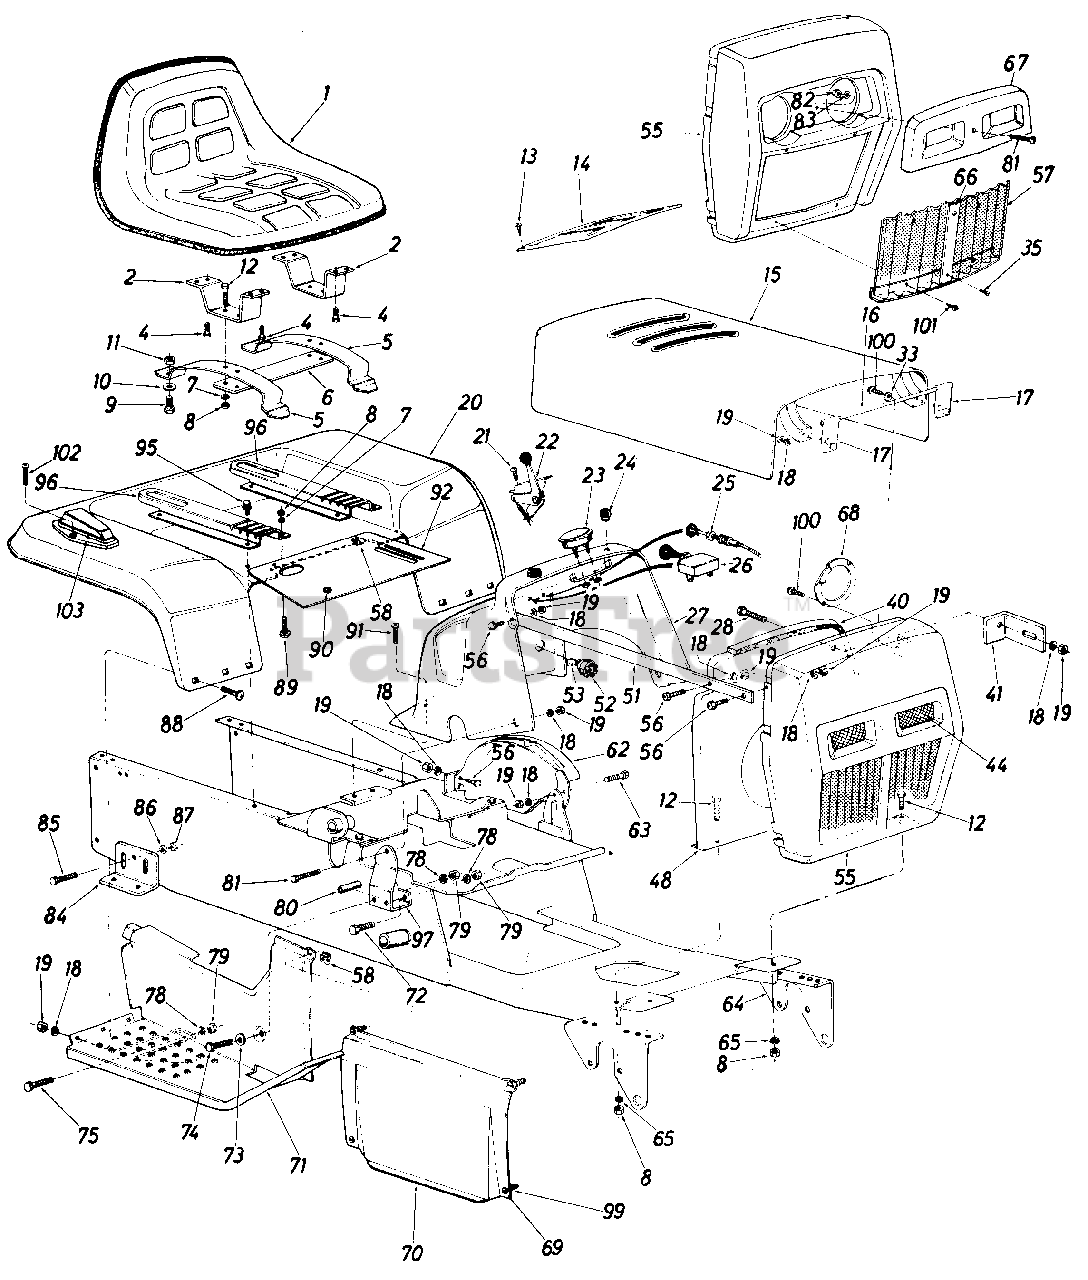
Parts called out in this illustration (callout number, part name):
1	Seat Ass'y. Comp.
2	Seat Support Brkt.
4	Hex Wash. Hd. Self-Tap Scr. 3/8-16 x .75" Lg.
7	L-Wash. 5/16" I.D.
8	Hex Nut 5/16-18 Thd.
9	Nylon Scr. 1/2-13 x .75" Lg.
10	Fl-Wash. .531 I.D. x .930 O.D.
11	Hex Cent. L-Nut '/2-13 Thd.
12	Hex Scr 5/16-18 x .75" Lg.
13	Self-Tap Oval Hd. Scr. 1/2" Lg.
14	Dash Panel Cover
15	Hood Ass'y.
16	Hinge Rod
17	Hood Hinge Ass'y.
18	L-Wash. 1/4" Scr.
19	Hex Nut 1/4-20 Thd.
20	Rear Fender
21	Fl-Hd. Truss Scr. #10 x .62" Lg.
22	Throttle Control
23	Ammeter
24	Rubber Bumper
25	Choke Control
26	Light Switch
27	Dash Panel
28	Hex Scr. 1/4-20 x .62" Lg.
33	Fl-Wash. .250 I.D. x 1.25 O.D.
40	Foam Strip
41	Heat Shield Brkt.
44	Head Lamp
48	Heat Shield
51	Grille Strap
52	Ignition Switch
53	Ignition Key
55	Grille
56	Hex Scr. 1/4-20 x .75" Lg.
57	Grille Screen
58	Clip-On Receptacle
62	Speed Control Guide
63	Truss Mach. Scr. 1/4-20 x .75" Lg.
64	Frame Ass'y.
65	Bell-Wash. 5/16" Scr.
66	Moulding
67	Headlight Bezel
68	Headlight Retainer
69	1/4-Turn Stud
70	Hood Lower Side Panel
71	Foot Step Panel Ass'y.-R.H.
72	Hex Scr. 3/8-16 x 1.00" Lg. Grade 5
73	Fl-Wash. .385 I.D. x,.62 O.D.
74	Hex Bolt 3/8-16 x 3.00" Lg.
75	Hex Bolt 3/8-16 x 1.00" Lg. Grade 5
78	L-Wash. 3/8" I.D.
79	Hex Nut 3/8-16 Thd.
80	Spacer .375 I.D. x .62 O.D. x 2.00" Lg.
81	Truss Mach. Scr. #10-24 x 1.0" Lg.
82	Sq. Nut #10-24 Thd.
83	Ext. L-Wash. #10 I.D.
84	Transaxle Support Brkt.
85	Rd. Hd. Rib Neck Scr. 3/8-24
86	L-Wash. 3/8" Scr.
87	Hex Nut 3/8-24 Thd.
88	Carr. Bolt 1/4-20 x .50" Lg.
89	Carr. Bolt 5/16-18 x .62" Lg.
90	Snap Bushing
91	Fl-Hd. Self-Tap Scr. 1/4-20 x .62" Lg.
96	Seat Adjustment Brkt.
100	Thread Rolling Scr. 1/4"
101	Drive Scr. #7
102	Fl. C-Sunk AB-Tap Scr. #10 x, 1.0" Lg.
103	Taillight
